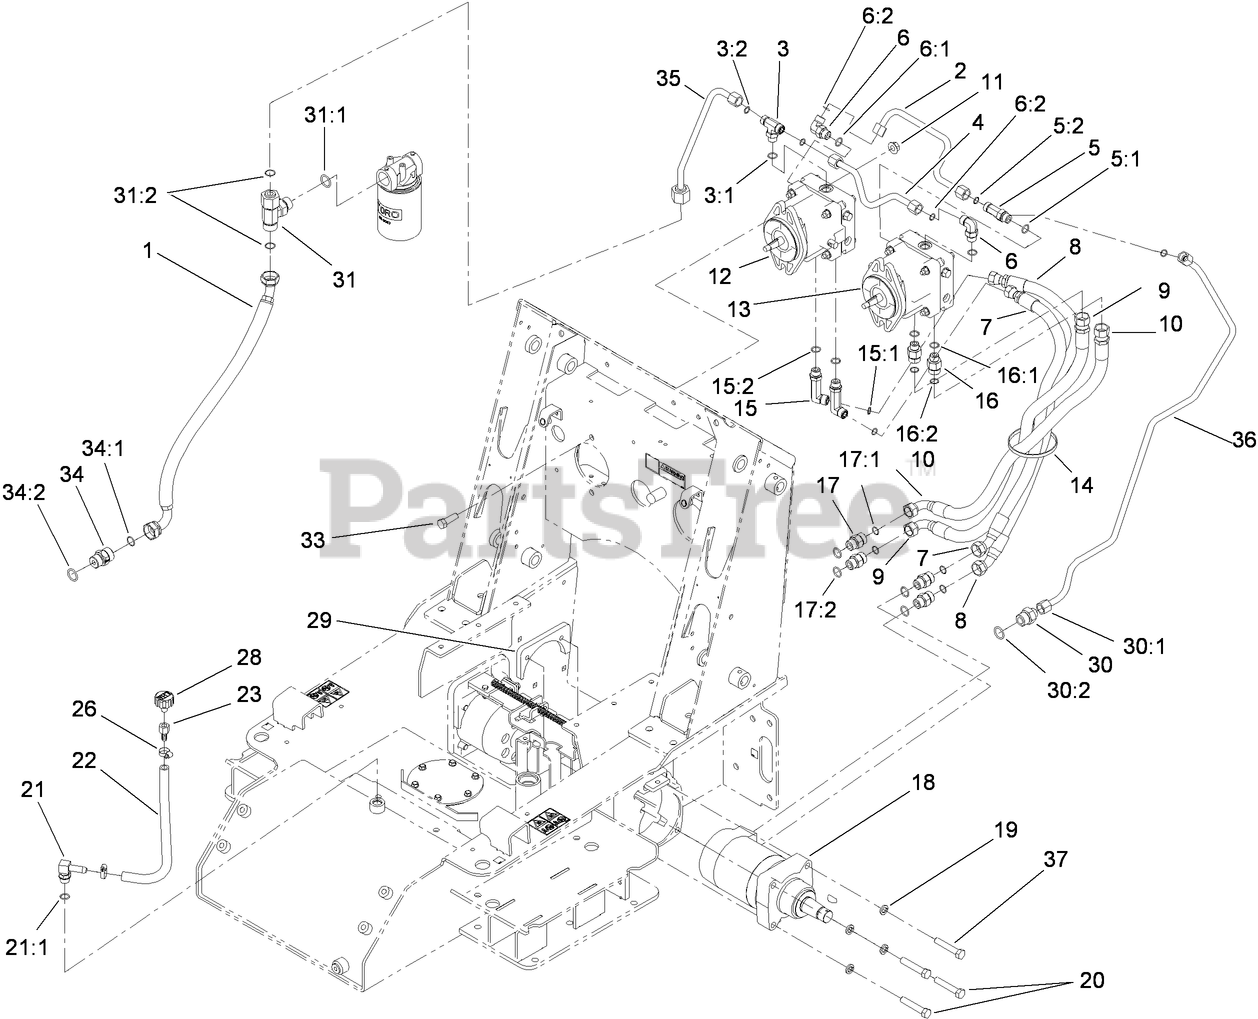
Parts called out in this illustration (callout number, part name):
1	HYD HOSE ASM
2	TUBE-HYD
3	FITTING-HYD, TEE
3:1	O-RING
3:2	O-RING
4	TUBE-HYD
5	FITTING-TEE
5:1	O-RING
5:2	O-RING
6	FITTING-ELBOW-90 DEG
6:1	O-RING
6:2	O-RING
7	HYD HOSE ASM
8	HYD HOSE ASM
9	HYD HOSE ASM
10	HOSE-HYD
11	NUT-LOCK, FLANGE
12	PUMP-HYD, RH
13	PUMP-HYD, LH
14	TIE-CABLE
15	FITTING-ELBOW, 90 DEG
15:1	O-RING
15:2	O-RING
16	FITTING-STR
16:1	O-RING
16:2	O-RING
17	FITTING-STRAIGHT
17:1	O-RING
17:2	O-RING
18	HYD MOTOR ASM
19	WASHER-LOCK
20	SCREW-HH, TAP
21	FITTING-HYD, 90 DEG
21:1	O-RING
22	HOSE-DRAIN, ENGINE OIL
23	FITTING-FEMALE, BARBED
26	CLAMP-HOSE
28	BREATHER
29	PLATE-MOUNTING
30	FITTING-STR
30:1	O-RING
30:2	O-RING
31	FITTING-TEE
31:1	O-RING
31:2	O-RING
33	SCREW-HH
34	VALVE-CHECK, HYD
34:1	O-RING
34:2	O-RING
35	HYD TUBE ASM
36	HYD TUBE ASM
37	SCREW-HH
